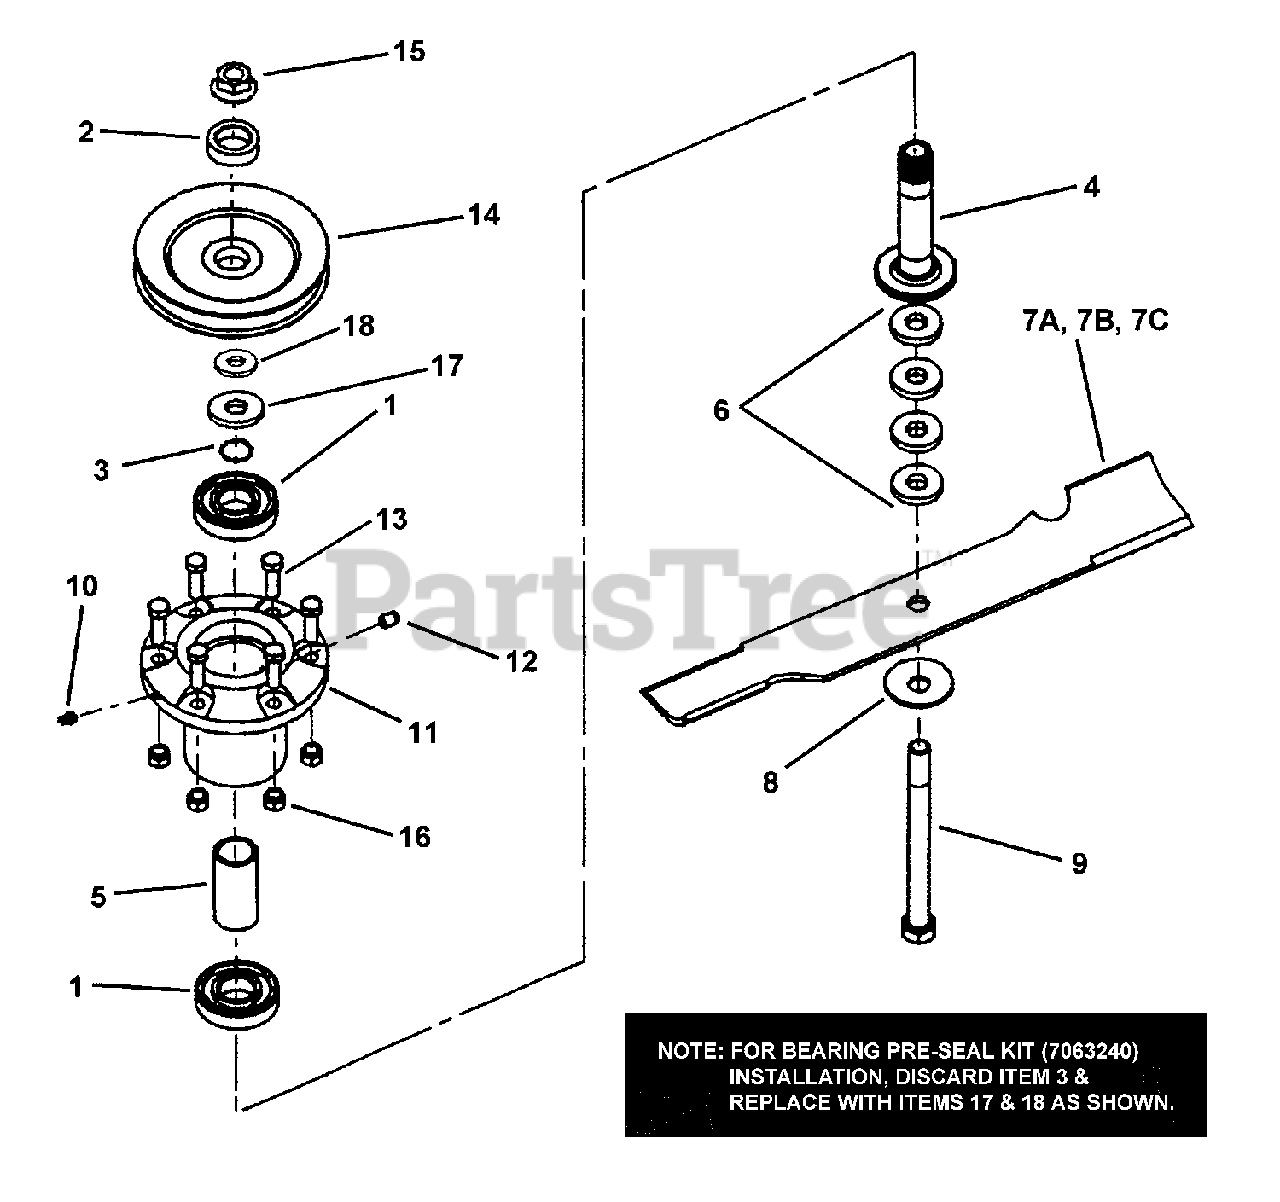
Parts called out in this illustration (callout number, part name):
1	BEARING, Sealed
2	WASHER, Spindle
3	SNAP-RING, Spindle Shaft
4	ASSEMBLY, Spindle Shaft
5	SPACER, Bearing
6	SPACER, Blade
7A	BLADE, 18" Comm. With Ext. Cut
7B	BLADE, 21"
7C	BLADE, 16-1/2"
8	WASHER, Beveled
9	BOLT, 5/8-11 x 7-1/2" Hex Head Cap, GR 5
10	LUBE FITTING, 1/4-28 Straight (Thread Forming)
11	* HOUSING, Cutter
12	GREASE VENT, Spindle
13	BOLT, 3/8-16 x 1-1/4" Rib Necked
14	PULLEY, 5-3/4" O.D.
15	NUT, 5/8-11 Hex Flange Lock, GR B
16	NUT, 3/8-16 HEX NYLON LOCK
17	** SEAL, Nylos
18	** WASHER
